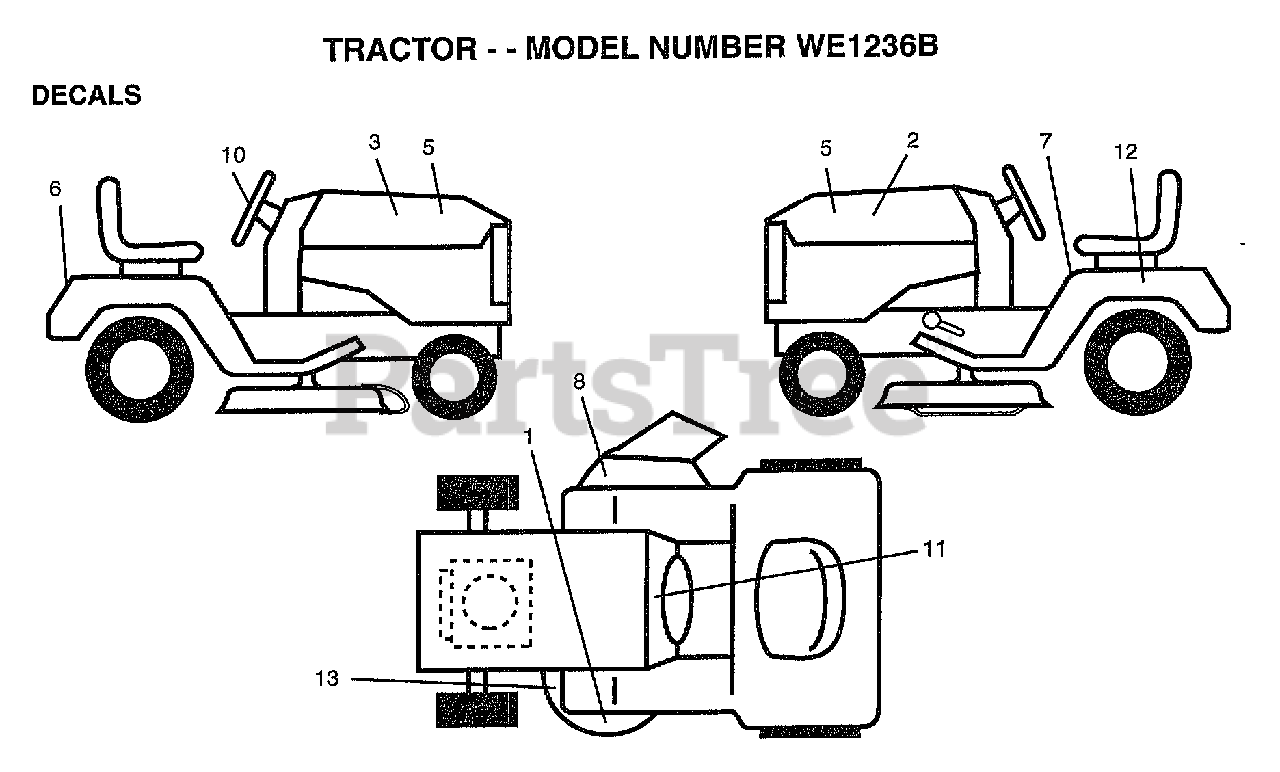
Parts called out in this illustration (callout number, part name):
1	DECAL.MOWER
2	DECAL STRIP HD LH
3	DECAL STRIP HD RH
5	DECAL PNL SIDE RH
6	DECAL.FENDER
7	DECAL CAUT FEND
8	"DECAL, WARNING"
10	DECAL.WHL.STRG.
11	DECAL OP INST E/S
12	DECAL.FEND.QUICKS
13	DECAL.V.BELT
